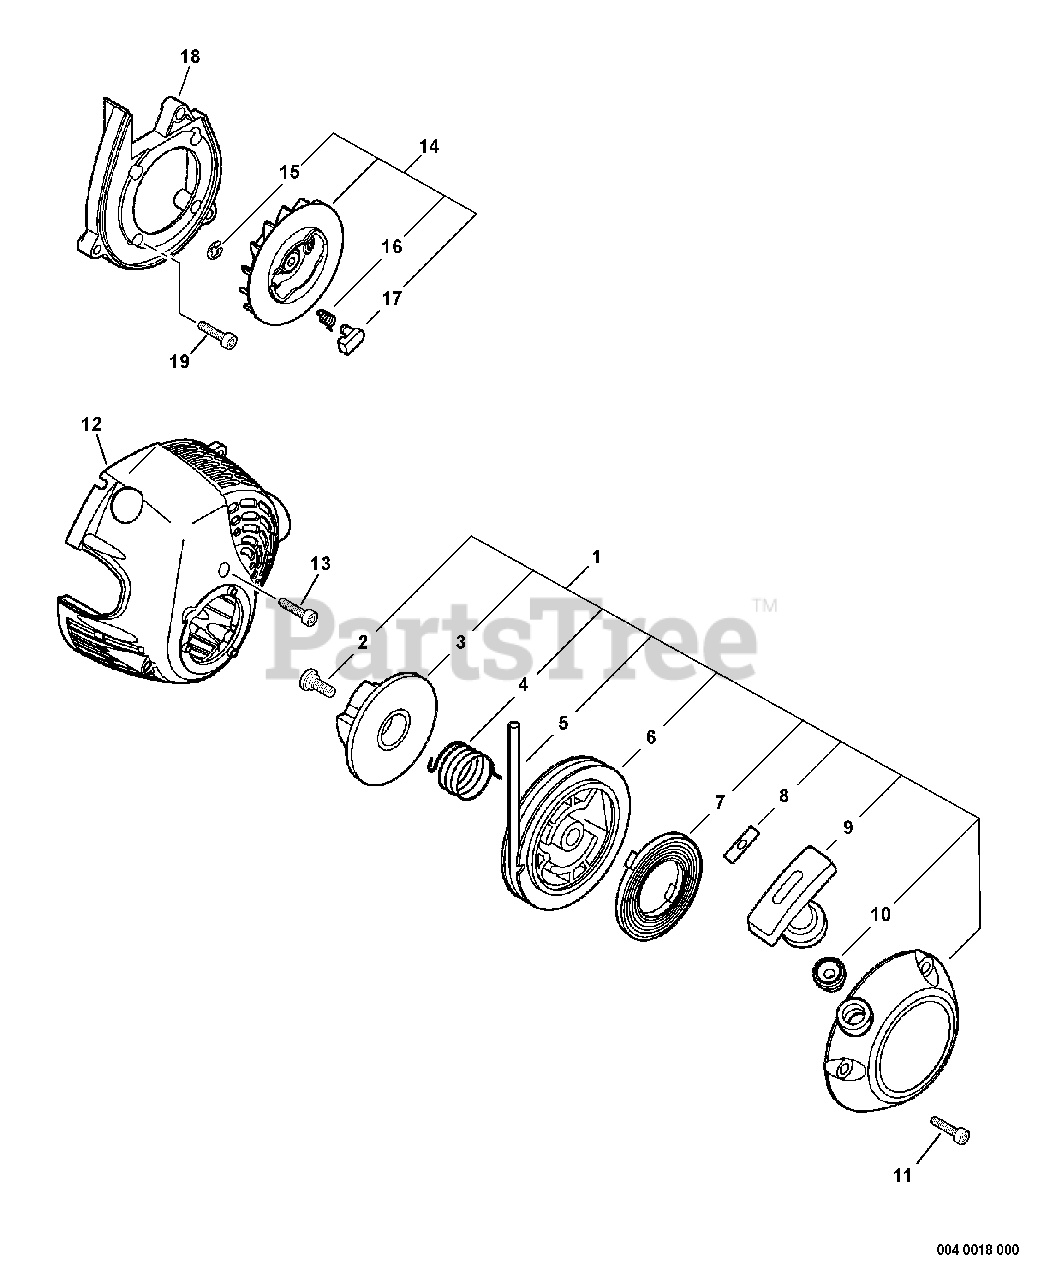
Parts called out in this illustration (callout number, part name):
1	STARTER ASSY, RECOIL
2	SCREW
3	PLATE, CAM (NLA SEE PB 15-06)
4	SPRING, TORSION
5	ROPE, STARTER 3×700
6	REEL, ROPE
7	SPRING, RECOIL
8	RETAINER, ROPE
9	GRIP, STARTER
10	GUIDE, ROPE
11	SCREW TAPPING 5×16
12	COVER, ENGINE
13	SCREW TAPPING 5×20
14	PAWL ASSY, STARTER
15	E-RING 4
16	SPRING, RETURN
17	PAWL, STARTER
19	BOLT 4×16
